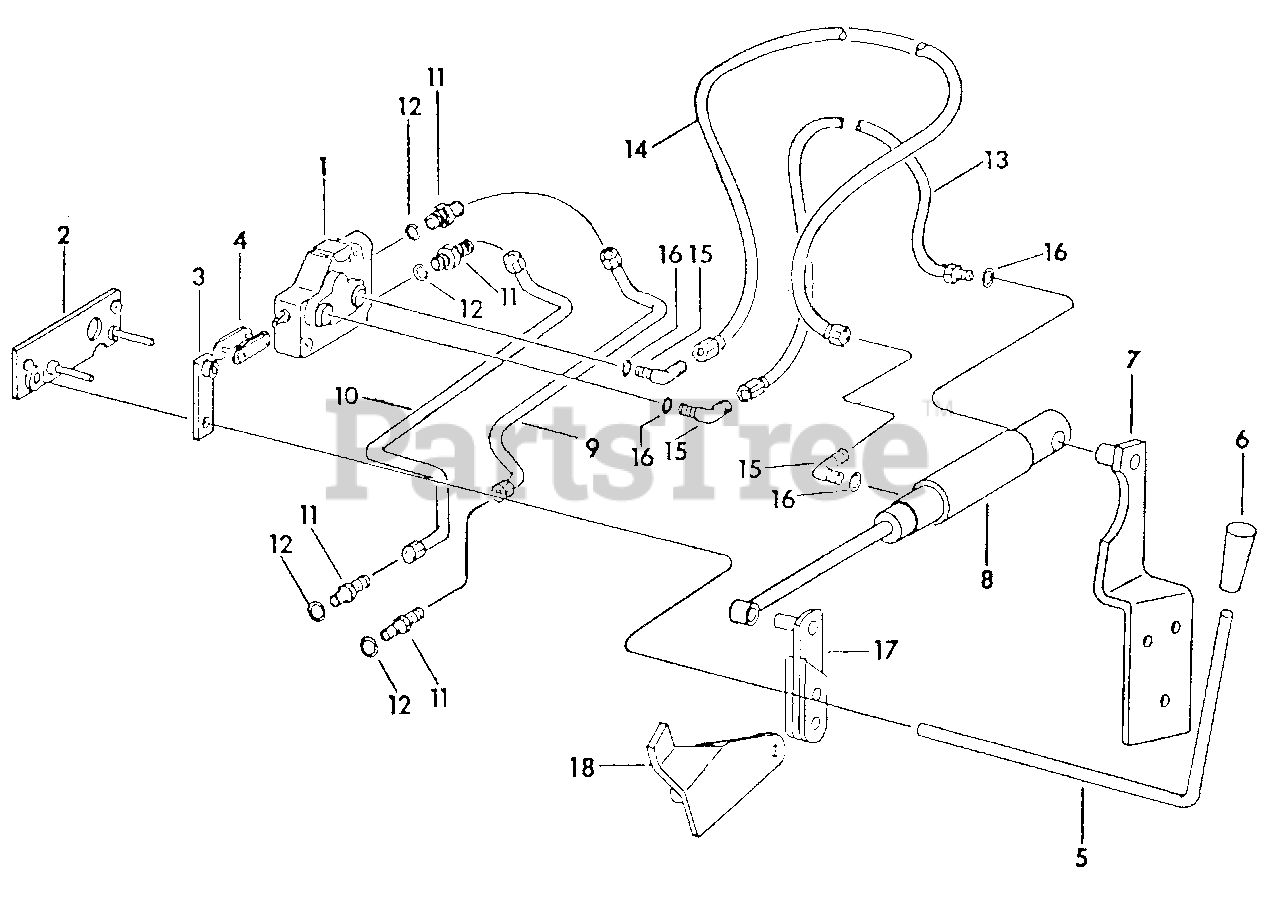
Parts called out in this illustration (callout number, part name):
1	Valve Assy, Control
2	Plate Assy, Valve Mtg
3	Lever Assy, Valve Handle
4	Link, Chain
5	Handle, Valve
6	Grip, Handle
7	Bracket Assy, Lift
8	Cylinder, Lift
9	Tube Assy, Return
10	Tube Assy, Pressure
11	Union, 37 Deg Flared Short Swivel Tube
12	O-Ring, 3/8 OD Tube
15	Elbow, 90 Deg Tube
16	O-Ring, 3/8 OD Tube
17	Clevis Assy, Hyd Lift
18	Plate Assy, Rockshaft
